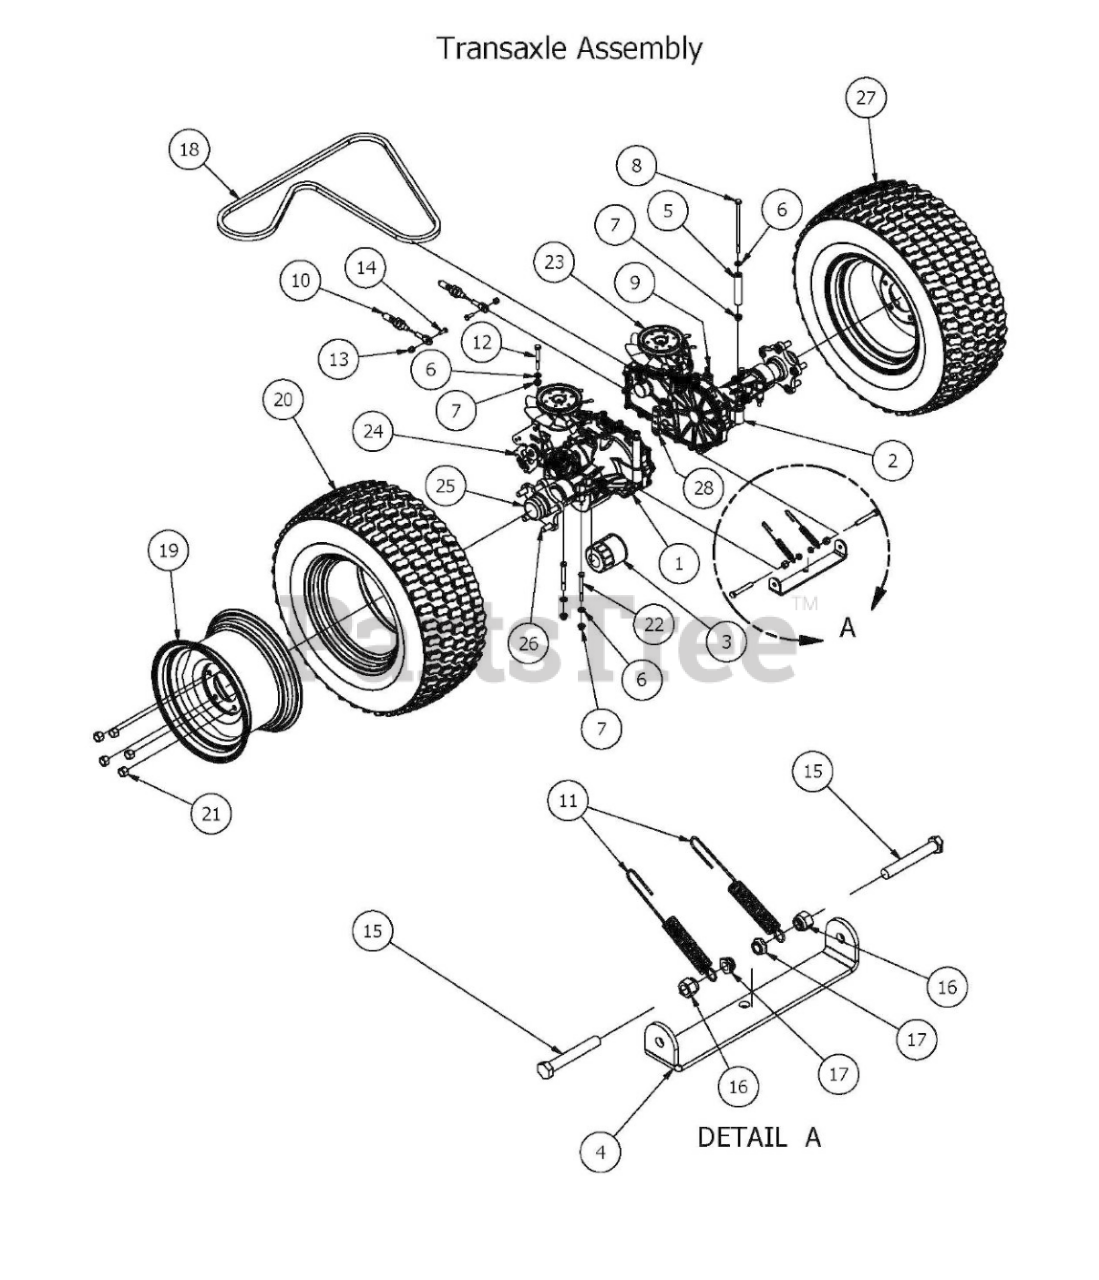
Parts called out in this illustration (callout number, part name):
1	Left 3400 IZT
2	Right 3400 IZT
3	Hydraulic Filter
4	Crossover Bar for ZT 2016
5	2017 Transaxle Spacer
6	5/16" Flat Washer
7	5/16" Nylock Flange Nut
8	5/16" x 6" Bolt
9	45 degree fitting
10	Brake Cable
11	Brake Spring
12	16" x 2 1/2" Bolt
13	1/4-20 Nylon Insert flange Nut
14	1/4" x 3/4" Hex Bolt
15	3/8 x 2 1/2 Hex Tap Bolt
16	3/8 Nylock Nut
17	3/8 Nylock Jam Nut 1/2 Nut
19	12" x 7"Black Wheel
20	23 x 8.50 -12 Tire
21	Acorn Lug Nut
22	5/16" x 3" Hex Bolt
23	Fan/Pully kit
24	Transaxle Spring
25	Transaxle Hub
26	Transaxle Wheel Studs
27	Wheel and Tire Assembly (19 and 20)
28	Transaxle Brake Lever
